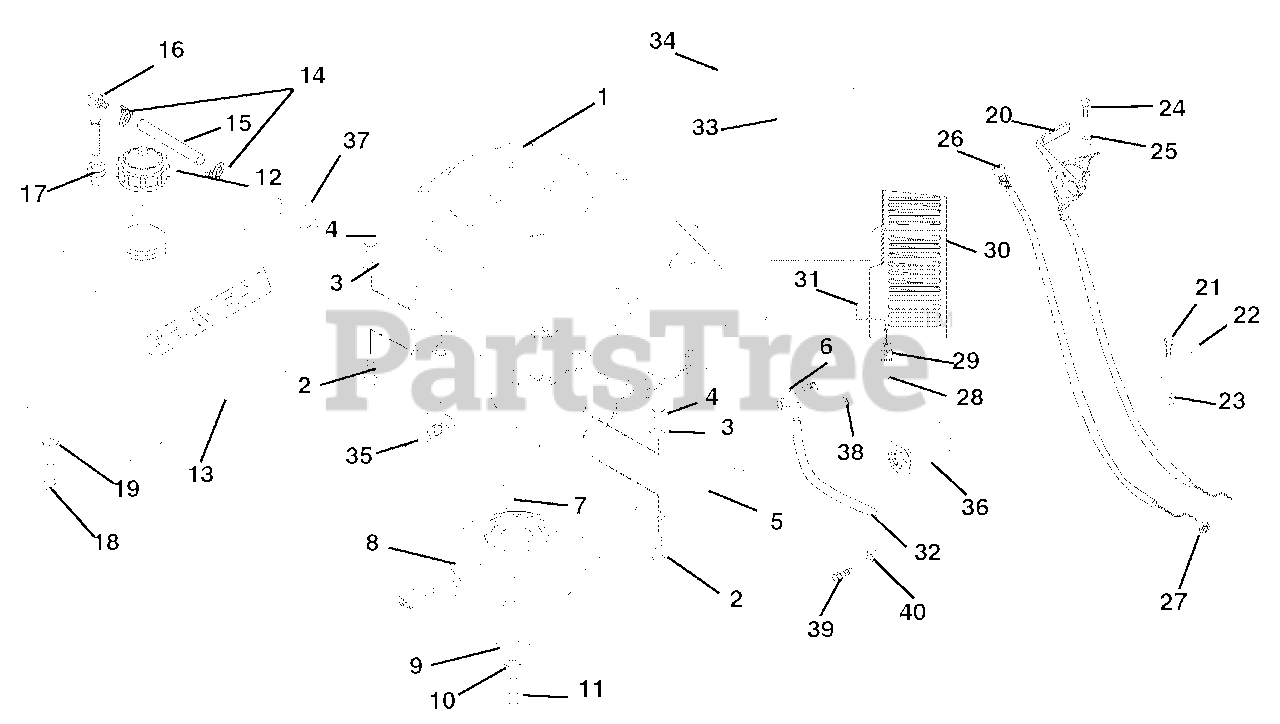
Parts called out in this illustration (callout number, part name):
1	Engine, 17 HP Kawasaki(108, 109)
2	Bolt-Hex .31-18 x 1.75 Grade 5
3	Washer-Locking .31 x .078 Regular
4	Nut-Hex .31-18
5	Bracket, Clutch
6	Valve, Oil Drain
7	Key-Square .25 x 1.25 x 25 SAE 8630 OR SAE 1035
8	Clutch, Electric
9	Washer-Flat-Steel .469 x 2.00 x .25
10	Washer-Locking .44 x .109 Regular
11	Bolt-Hex .44-20 x 3.00 Grade 5
12	Cap- Gas
13	Tank, Fuel
14	Clamp-Hose Wire .49/.51 x .116
15	Gas Line-Bulk .25 I.D.
16	Fitting, Tank
17	Bushing
18	Bolt-Hex .38-16 x .75 Grade 5
19	Washer-Locking .38 x .094 Regular
20	Cable, Throttle-with Liner
21	Bolt-Hex .31-18 x .75 Grade 5
22	J-Clamp
23	Nut-Locking-Nylon .312-18
24	Screw-Machine 10-24 x .75 Hex Washer Head
25	Nut-Locking-Nylon 10-24 with Insert
26	Control,Choke
27	Nut-Jam .375-24
28	Bolt-Hex .38-16X1.00 Grade 5 (312)
29	Bracket, Muffler Guard (312)
30	Guard, Muffler (312)
31	Nut-Locking-Center .38-16 (312)
32	Hose,.25 In Vinyl
33	Filter, Air Paper (105 - 107, 113, 312)
34	Filter, Air Foam (105 - 107, 113, 312)
35	Spark Plug
36	Filter, Oil
37	Fuel Filter- Kawasaki
38	Nut-Locking-Center .31-18 (312)
39	Bolt-Hex .38-16 x .75 Grade 5 (312)
40	Nut-Locking-Center .38-16 (312)
